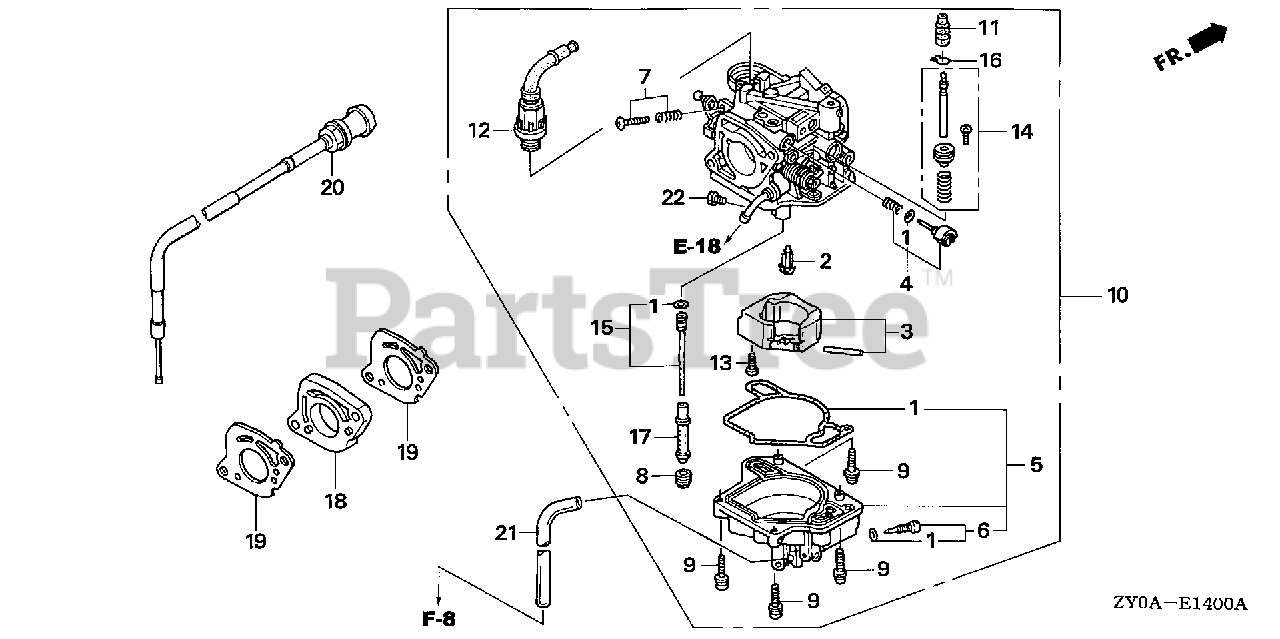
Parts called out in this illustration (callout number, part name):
1	GASKET SET
2	VALVE SET, FLOAT
5	CHAMBER SET, FLOAT
6	SCREW SET, DRAIN
7	SCREW SET
8	SCREW, PLUG
9	SCREW-WASHER
10	CARBURETOR ASSY. (BJ08A A)
12	VALVE SET, STARTER
13	SCREW, PAN
14	PLUNGER SET, ACCELERATOR PUMP
15	JET SET (#55)
16	CLIP, TUBE
17	NOZZLE, MAIN
18	INSULATOR, CARBURETOR
19	GASKET, CARBURETOR
20	CABLE, CHOKE
21	BULK HOSE, VINYL (4X7X8000) (4X7X200)
22	JET, MAIN (#120)
22	JET, MAIN (#122)
22	JET, MAIN (#125)
